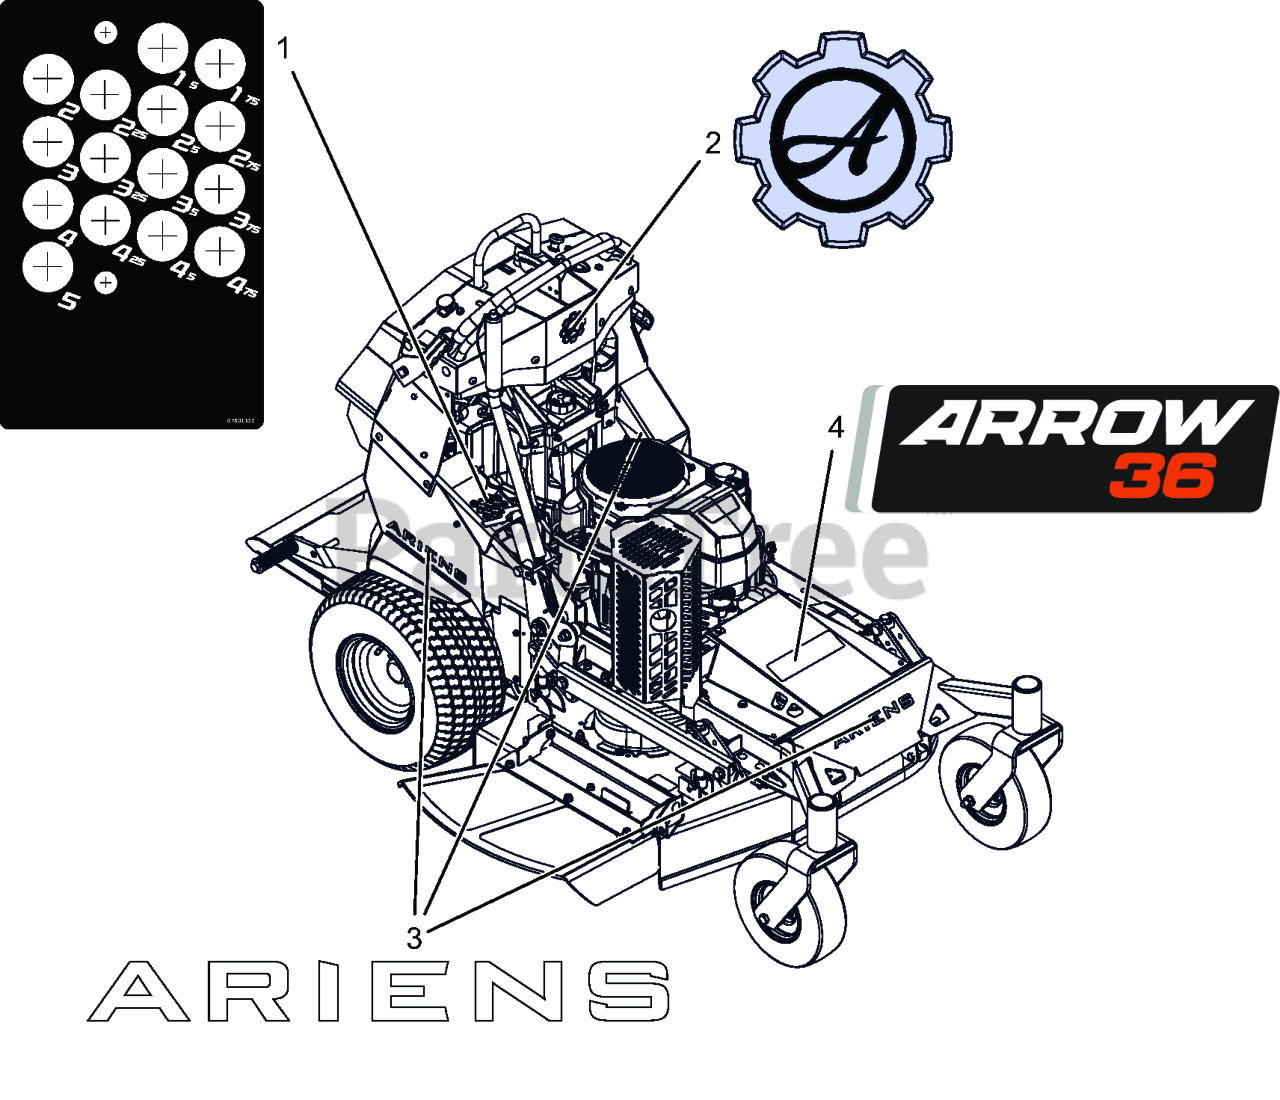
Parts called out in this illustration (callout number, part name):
1	DECAL, PRO STANCE - 32-36 HOC
2	DECAL- ARIENS GEAR BADGE
3	DECAL - ARIENS 9.625"
4	DECAL, ARROW 36
